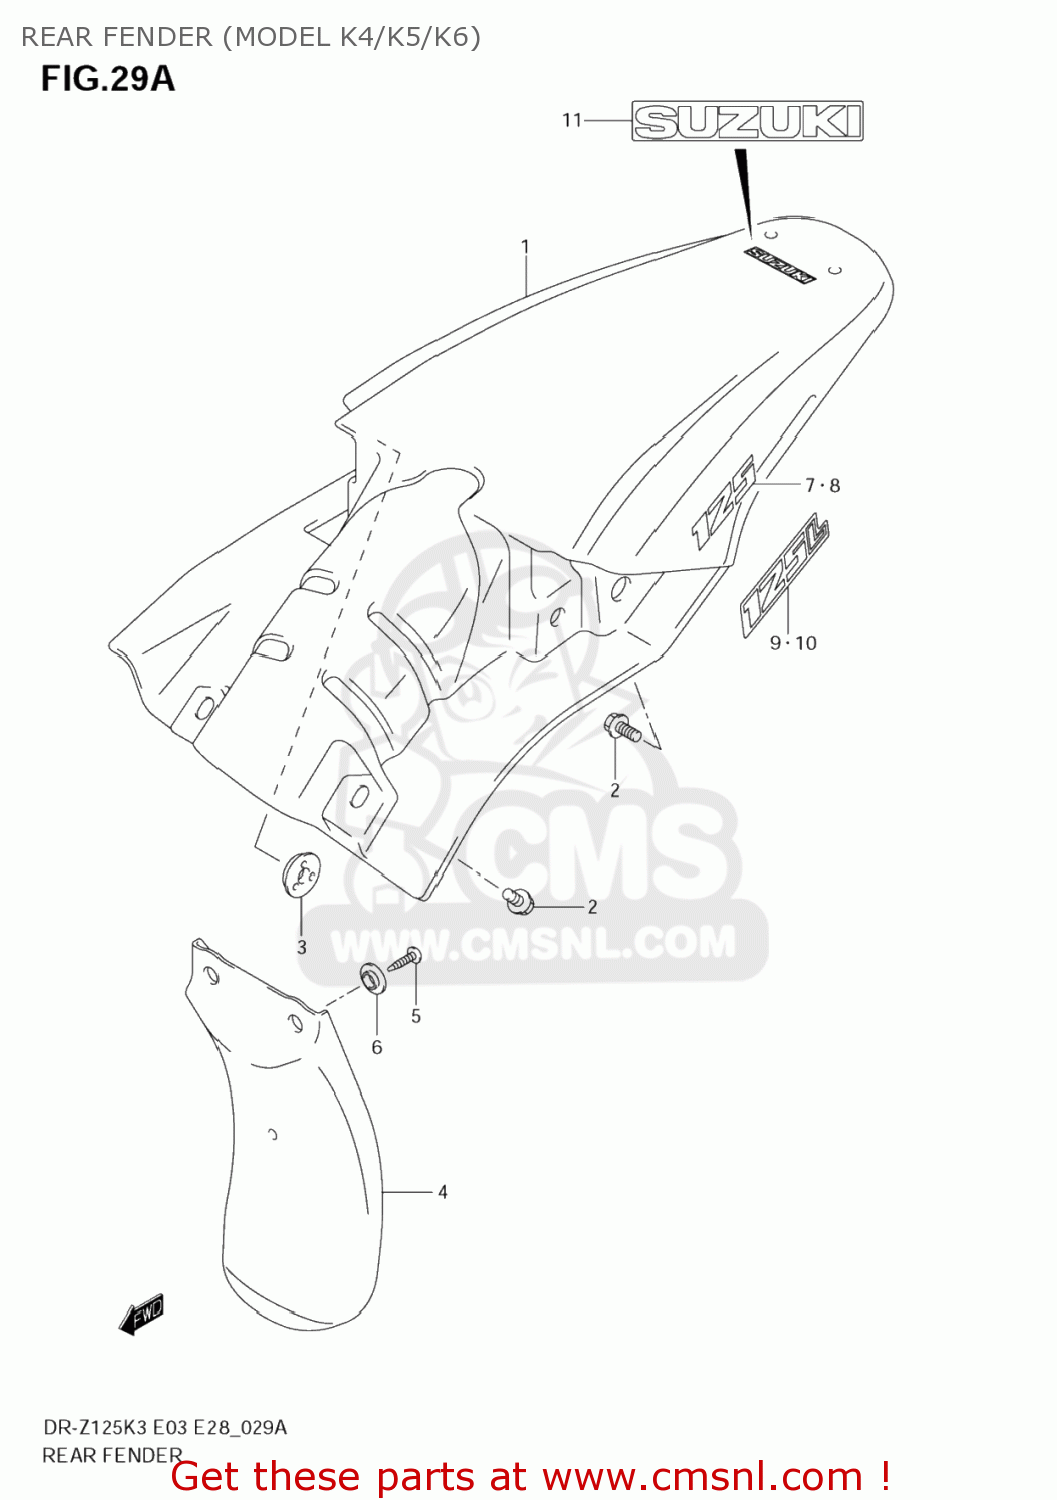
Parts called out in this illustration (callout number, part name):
1	FENDER,RR
2	BOLT
3	WASHER
4	MUDGUARD,RR FENDER FR
5	SCREW
6	WASHER
7	EMBLEM,125,R
8	EMBLEM,125,L
9	EMBLEM,125,R
10	EMBLEM,125,L
11	EMBLEM,SUZUKI
